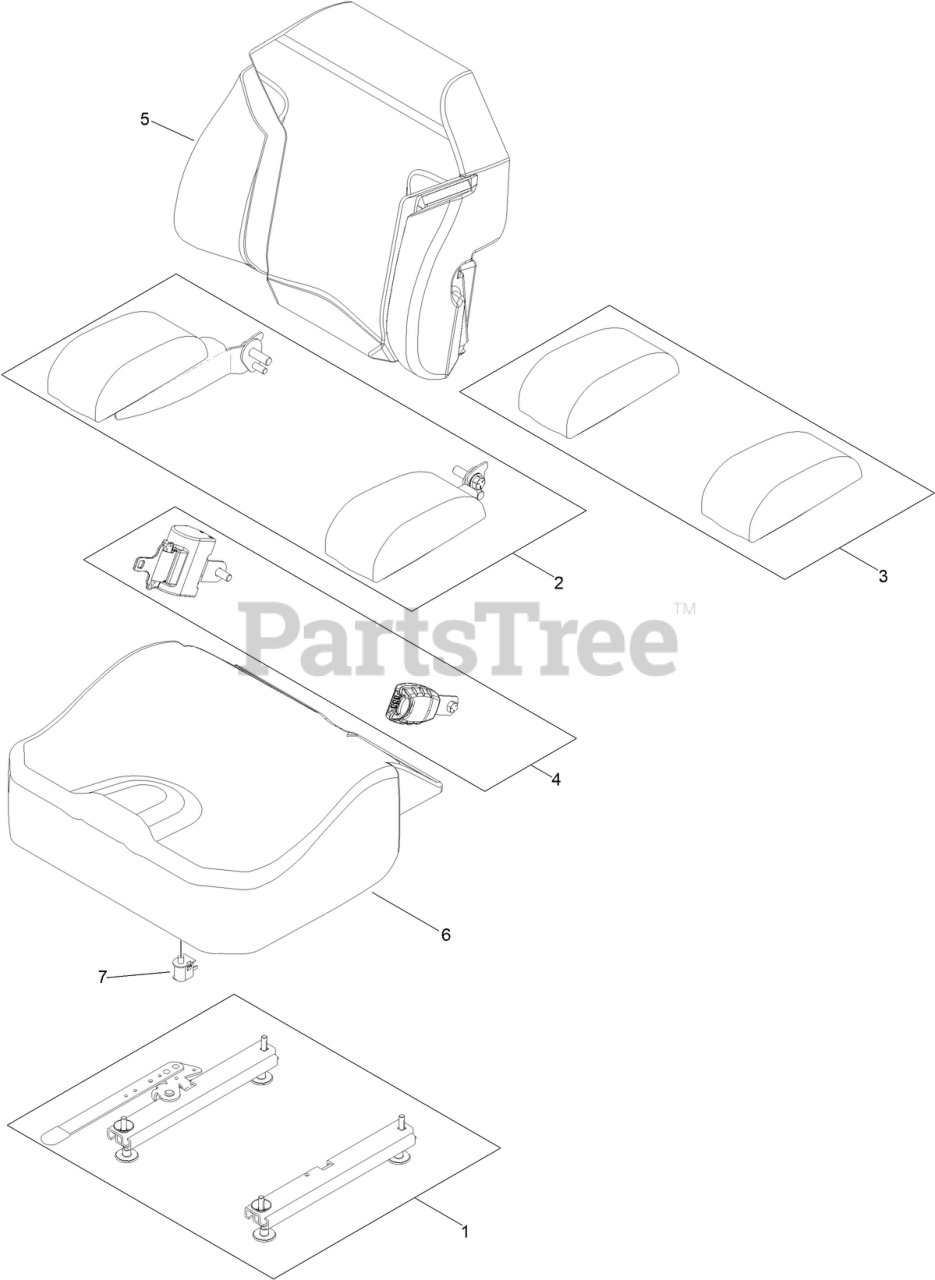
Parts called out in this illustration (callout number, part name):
1	SEAT TRACK KIT
2	ARMREST KIT
3	PADS-ARMREST
4	SEAT BELT KIT
5	COVER-BACK, SEAT
6	COVER-BOTTOM, SEAT
7	SWITCH-BAIL
